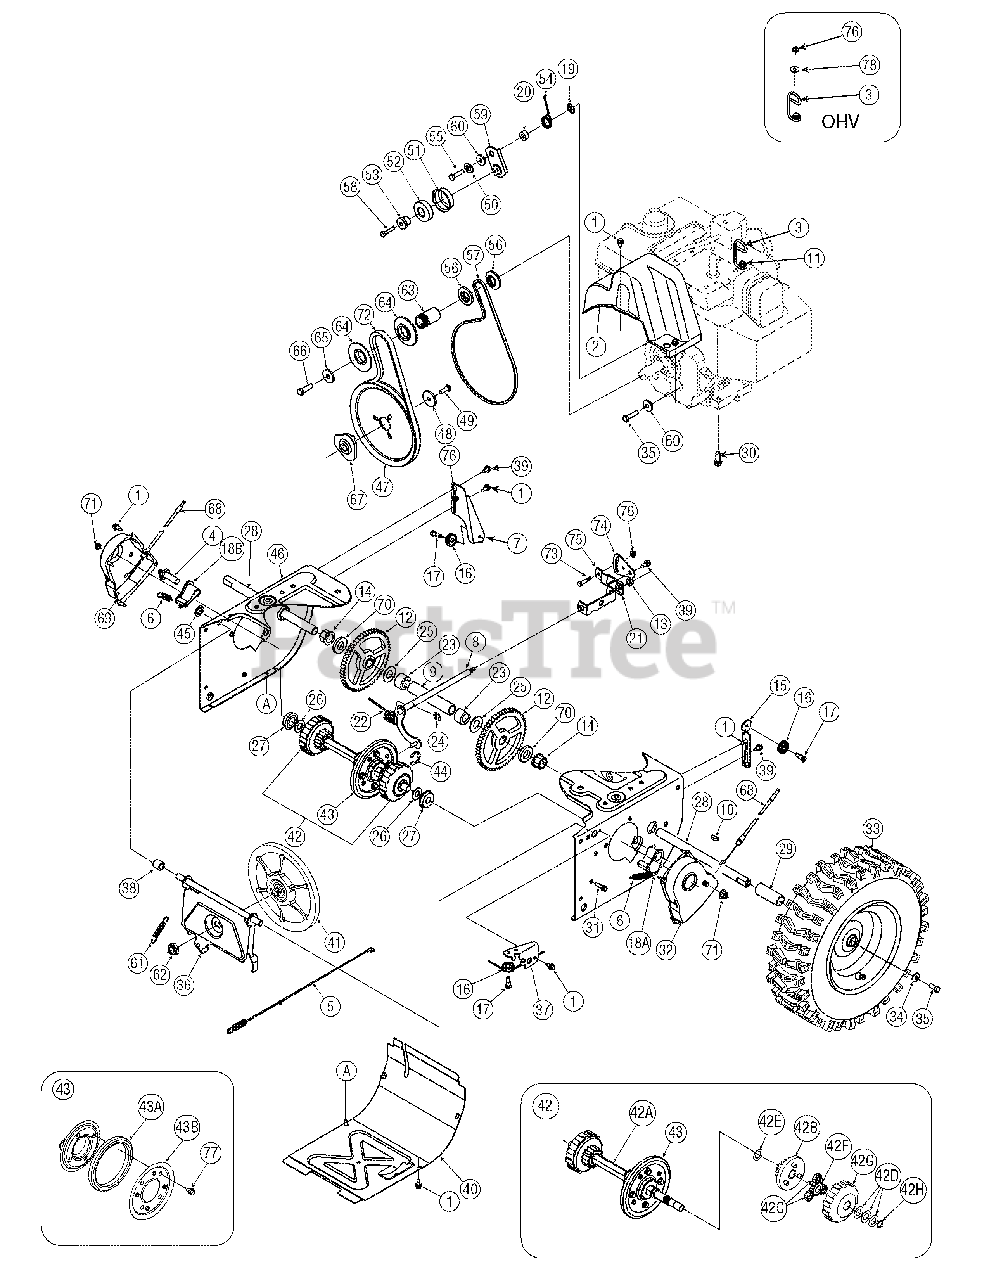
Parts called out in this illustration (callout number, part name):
1	Hex Wash Hd TT Scr. 1/4-20 x .625
2	Belt Cover (w/4 Way Chute Control)
2	Belt Cover (Std.)
3	Cable Control Wire
4	Drive Shaft Actuator
5	Drive Clutch Cable 44.83" Lg.
6	Extension Spring .5 OD x 1.71 Lg.
8	Shift Rod Ass’y
9	Axle Support Tube
10	#9 HI-Pro Key 3/16 x 3/4 Dia HT
11	Hex Wash Hd Tapp Scr 5/16-18 x 1.00
12	Gear, 56T
13	Flange Lock-Nut 5/16-18 Gr. F Nylon
14	Hex. Flange Bearing.751" ID
16	Cable Guide Roller
17	Hex Shld.Scr.1/4-28 x .375
18A	Dogg Assembly - LH
18B	Dogg Assembly - RH
20	Spacer .340 x .750 x .360" Lg.
21	Shift Spacer Bracket
22	Torsion Spring .750 ID x .968" Lg.
24	Retaining Ring
25	Flat Washer .760 ID x 1.49 OD
26	Flat Washer .580 x 1.125 x .080
28	Axle
30	Hex Wash HD Tap Scr 3/8-16 x .88
31	Hex Bolt 1/4-20 x 1.00
33	Axle
34	Cupped Washer .345 ID x .88 OD x .060
35	Hex L-Bolt 5/16-24 x .75 Gr. 5
38	Spacer .513 ID x 1.0
39	Shoulder Screw .373 x .105:TT 1/4-20
42	Drive Shaft Assembly (w/o Friction Wheel Ass'y)
42A	Hex Drive Shaft (500)
42B	Planetary Carrier Ass'y
42D	Flat Washer .58 x 1.12 x .02
42E	Flat Washer 5/8 ID x 1.0 OD
42G	Ring Planetary Gear Ass'y (500)
42H	Retaining Ring 1.56 diam.
43	Friction Wheel Assembly
43A	Friction Wheel Rubber
43B	Friction Plate
44	Retainer Ring
45	Cap Speed Nut 1/4 Rod
48	Flat Washer .34 x 1.50 x .150
49	Hex Bolt 5/16-24 x 0.875
50	L-Wash 5/16 ID
51	Bearing Sleeve
52	Ball Bearing 20 x 47 x 14:6204:DS
54	Torsion Spring .850 ID x .354" Lg.
55	Hex HD. Cap Scr. 5/16-24 x 1.25 Lg.
56	Pulley HalfL 1/4 V x 1.5 OD
57	Belt 33.0" Lg.
58	Hex Bolt 1/4-20 x 1.25
59	Wheel Drive Idler Bracket
60	Shoulder Spacer
61	Extension Spring 3/8 OD x 2.50
62	Jam L-Nut 5/8-18 Gr. 5 Nylon
63	Spacer .875 ID x 1.185 OD
64	Pulley Half
65	Flat Washer .40 ID x 1.25 OD x .160
66	Hex Screw 3/8-24 x 1.25
67	PulleyAdapter
68	Steering Cable
71	Flange Lock-Nut 3/8-16 Gr. F Nylon
72	Belt .5 x 35.0" Lg.
73	Hex Bolt 1/4-20 x .62 Gr. 5
76	Flange Lock-Nut 1/4-20 Gr. F Nylon
77	Hex Wash. Hd. TT Scr. 1/4-14 x .625
78	Flat Washer .28 ID x .74 DE x .063
